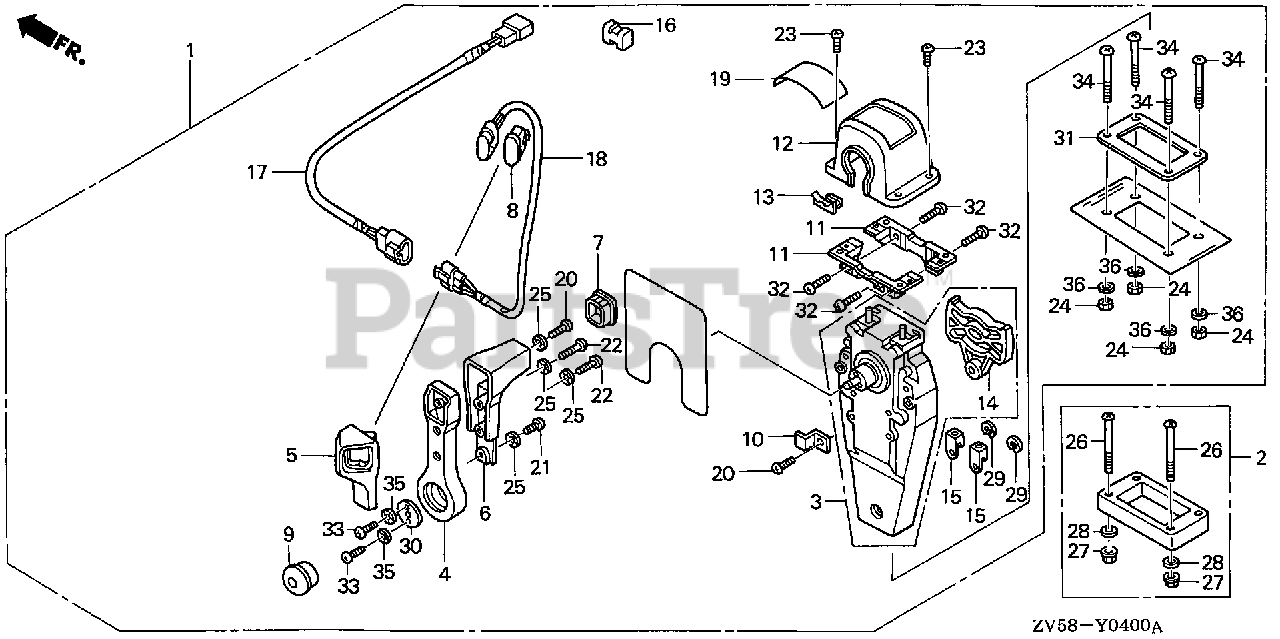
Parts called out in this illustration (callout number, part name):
1	BOX KIT, R. REMOTE CONTROL (TOP MOUNT SINGLE)
2	SPACER KIT, REMOTE CONTROL BOX (TOP MOUNT SINGLE)
3	HOUSING ASSY., L. (INNER) (TOP MOUNT)
4	HANDLE, REMOTE CONTROL
5	COVER, L. GRIP
6	GRIP, REMOTE CONTROL HANDLE
7	CAP, GRIP
8	CAP, SWITCH
9	BUTTON, THROTTLE
10	PLATE, CABLE CLAMP
11	BRACKET, REMOTE CONTROL HOUSING
12	HOUSING, REMOTE CONTROL BOX
13	HOUSING, LEAD
14	PLATE, DWELL
15	TERMINAL, CABLE
16	SPACER, CABLE CLAMP
17	SUB-HARNESS ASSY., POWER TRIM-TILT (A)
18	SWITCH ASSY., POWER TRIM-TILT (A)
19	MARK, REMOTE CONTROL (SINGLE)
20	SCREW, PAN (5X16)
21	SCREW, PAN (5X10)
22	SCREW, PAN (5X20)
23	SCREW, PAN (4X10)
24	NUT, HEX. (5MM)
25	WASHER, LOCK (5MM)
26	SCREW, PAN (5X65)
27	NUT, FLANGE (5MM)
28	WASHER, PLAIN (5MM)
29	E-RING (6MM)
30	PLATE, HANDLE
31	GASKET, SINGLE
32	SCREW, PAN (5X18)
33	SCREW, PAN (6X18)
34	SCREW, PAN (5X40)
35	WASHER, LOCK (6MM)
36	WASHER, PLAIN (5MM)
